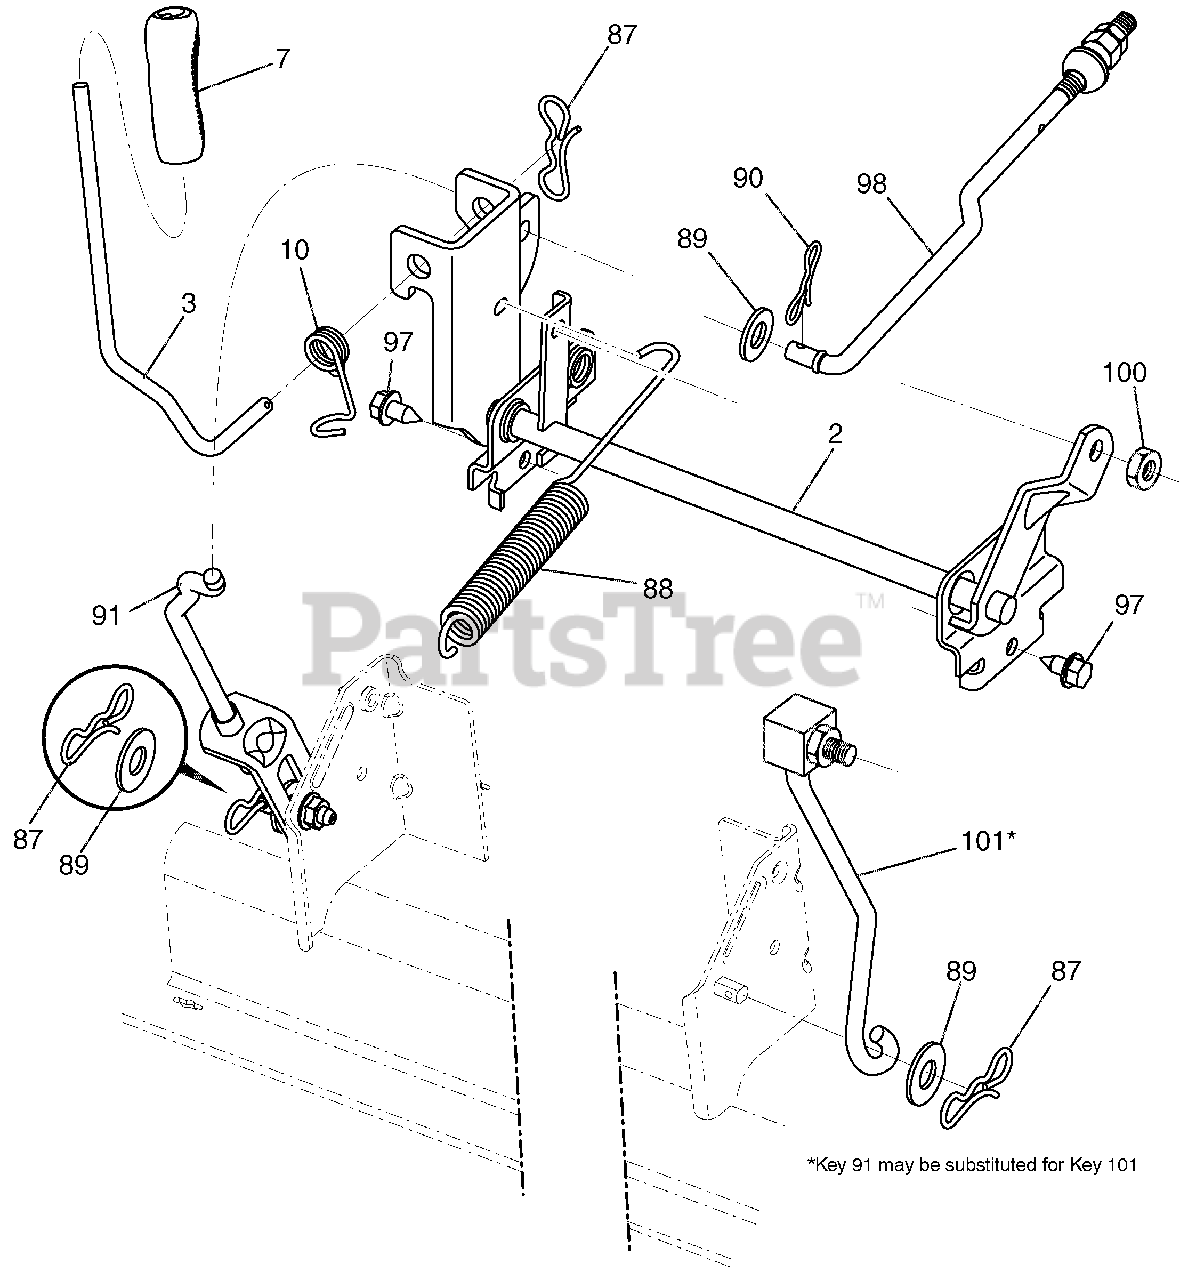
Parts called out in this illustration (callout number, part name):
2	SHAFT ASM., LIFT
3	LEVER.LIFT.HANDLE.LT
7	GRIP LEVER 5625 LD BLACK 428
10	SPRING.TORSION.HANDLE.LIFT
87	PIN.COTTER.7/16.BOW TIE LOCK
88	SPRING.LIFT ASSIST
89	WASHER.CLEAR ZINC
90	PIN.COTTER.5/16.BOW TIE LOCK
91	LINK.LIFT.SUSP.MOWER.REAR
97	SCREW.HEXWSH THDR3/8-16X3/4.BL
98	LINK.LIFT.SUSP.FRONT
100	NUT.CENTERLOCK.3/8-16 UNC.
101	LINK ASM.LIFT.FIXED
